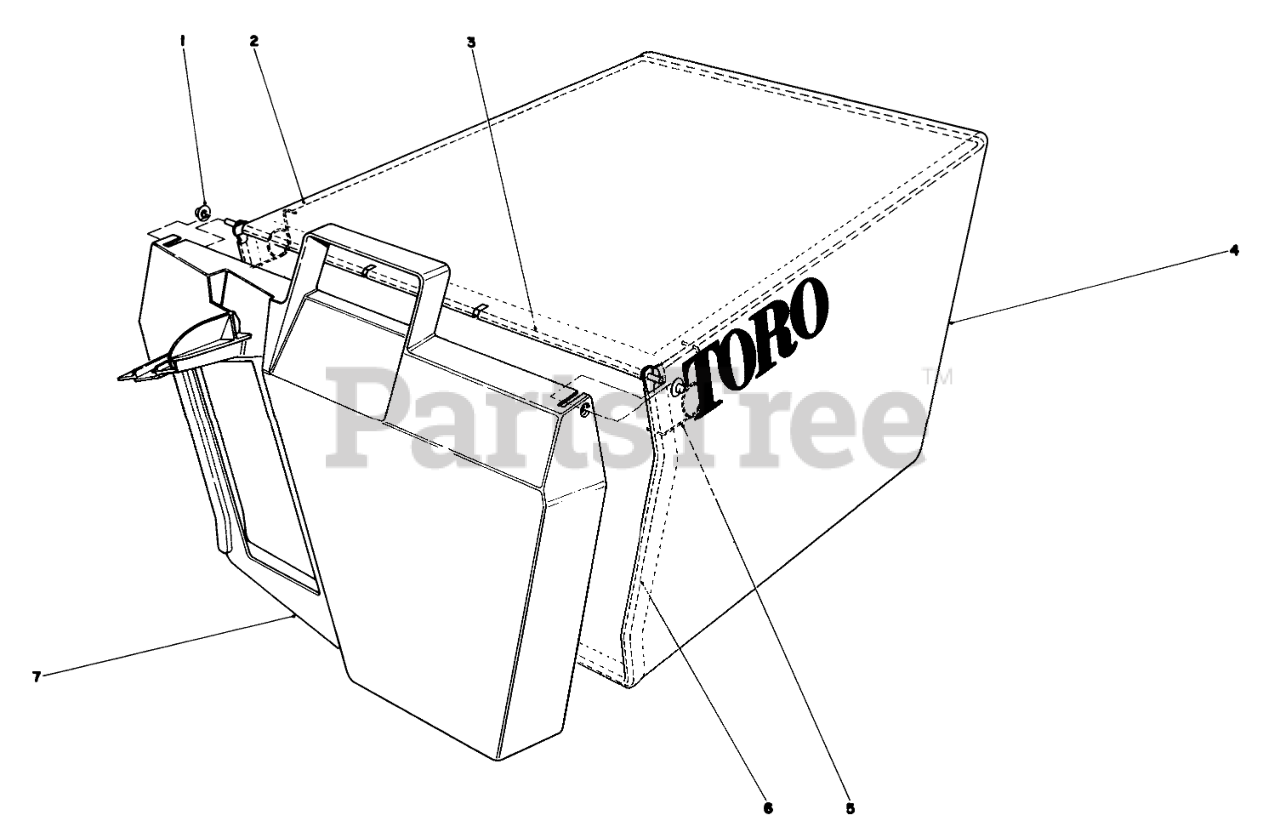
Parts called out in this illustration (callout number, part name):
1	NUT-PUSH
2	FRAME-BAG, UPPER
3	HINGE-DOOR, BAG
4	Bag
5	SPRING
6	BAG FRAME
7	Door Grass Bag
